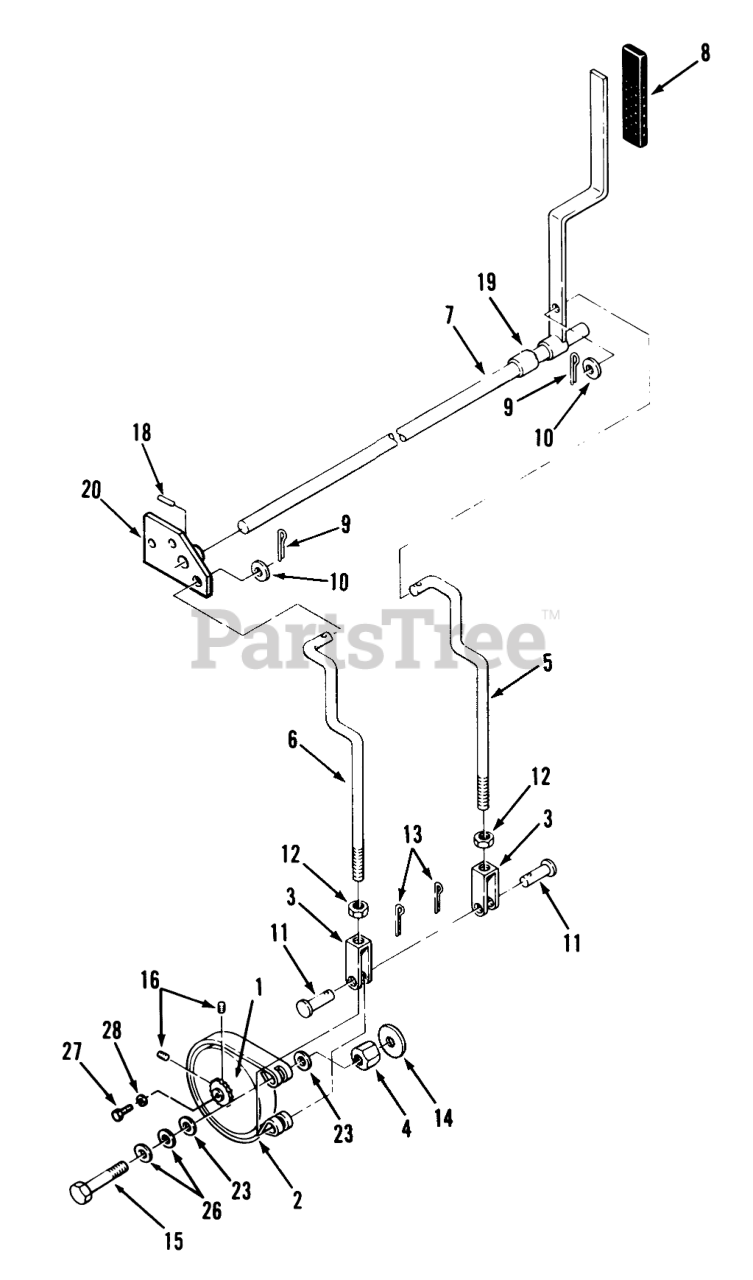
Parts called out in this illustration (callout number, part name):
1	ASS'Y-DRUM SPROCKET
2	BRAKE-BAND
3	ASSY-YOKE BRAKE
4	NUT-COUPLING
5	ROD-BRAKE L.H.
6	ROD-BRAKE R.H.
7	ASSY-PARKING BRK
8	GRIP BRAKE20258-K
9	Cotter Pin
10	WASHER 5/16 SAE
11	Clevis Pin 5/16 x 1 1/4
12	Nut-Lock
13	Cotter Pin
14	WASHER
15	Bolt
16	SCREW-SET
18	Roll Pin
19	SPACER-PARKING BR B
20	ASSY-PARKING BRK B
23	Washer
26	WASHER-SPRING
27	H H C S
28	WASHER
